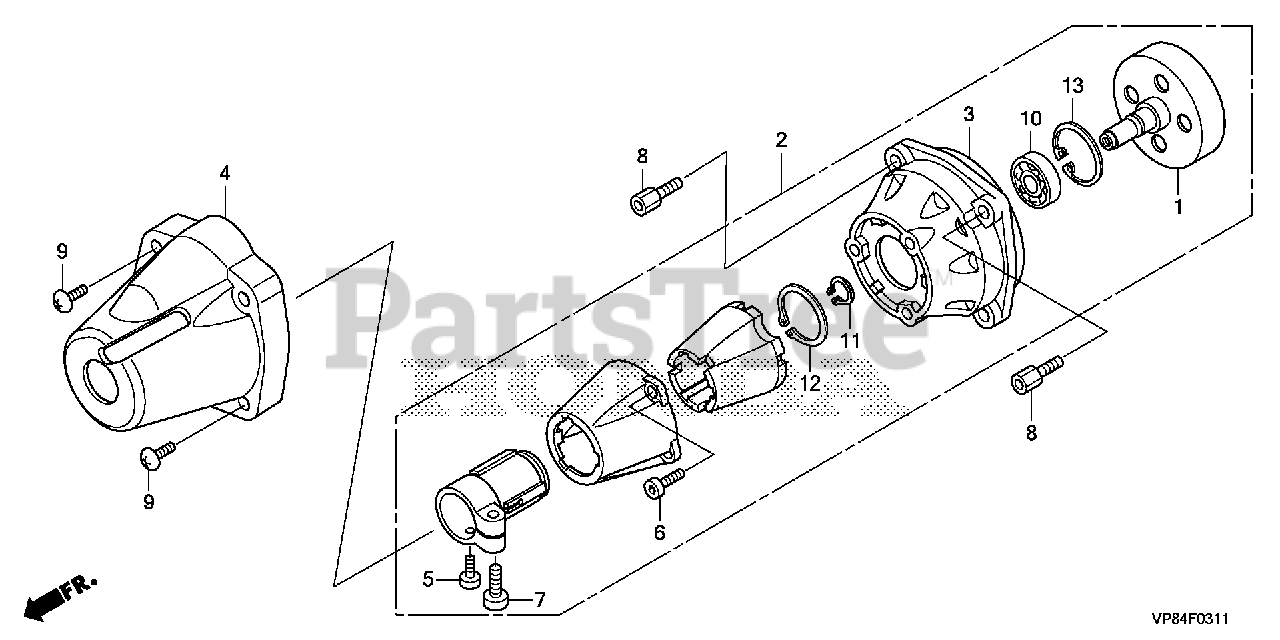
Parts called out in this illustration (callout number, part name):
1	CLUTCH OUTER
2	HOUSING ASSY., CLUTCH
3	HOUSING A, CLUTCH
4	COVER, CLUTCH HOUSING
5	BOLT, TORX (5X10)
6	BOLT, TORX (5X20)
7	BOLT, TORX (6X20)
8	BOLT, SPECIAL
9	SCREW, TORUS (5X12)
10	BEARING, RADIAL BALL (6202)
11	CIRCLIP (OUTER) (15MM)
12	CIRCLIP (OUTER) (30MM)
13	CIRCLIP (INNER) (35MM)
